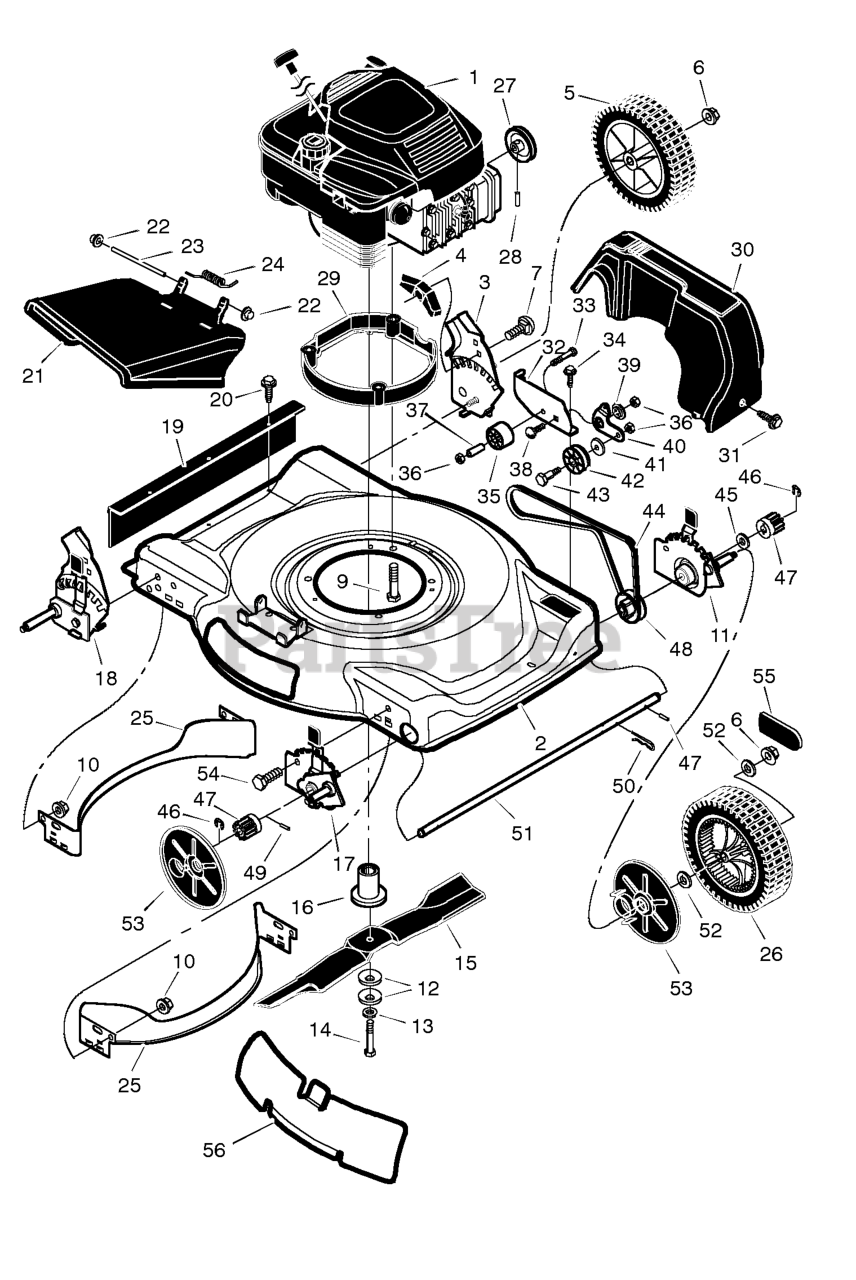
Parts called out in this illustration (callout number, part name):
1	Engine *
2	Housing
3	Height Adjuster, Left Rear
5	Wheel and Tire, Rear
6	Locknut, Flange
7	Bolt, Carriage
9	Bolt, Engine
10	Nut
11	Height Adjuster, Left Front
12	Washer, Belleville
14	Bolt, Hex
16	Adapter, Blade
17	Height Adjuster, Right Front
18	Height Adjuster, Right Rear
19	Guard, Rear
21	Deflector, Chute
22	Push- On Cap
23	Pin, Pivot
26	Wheel and Tire, Drive
28	Pin, Spring
29	Base, Engine
30	Cover, Belt
32	Bracket, Idler Support
36	Locknut
37	Bearing
38	Bolt, Carriage
40	Arm, Idler
42	Pulley, Idler
43	Bolt, Shoulder
46	Ring, Retainer
47	Gear, Pinion
49	Pin, Drive
50	Pin, Hair
52	Washer
53	Cover, Dust
54	Bolt
55	Hub Cap
56	Plate, Mulch
